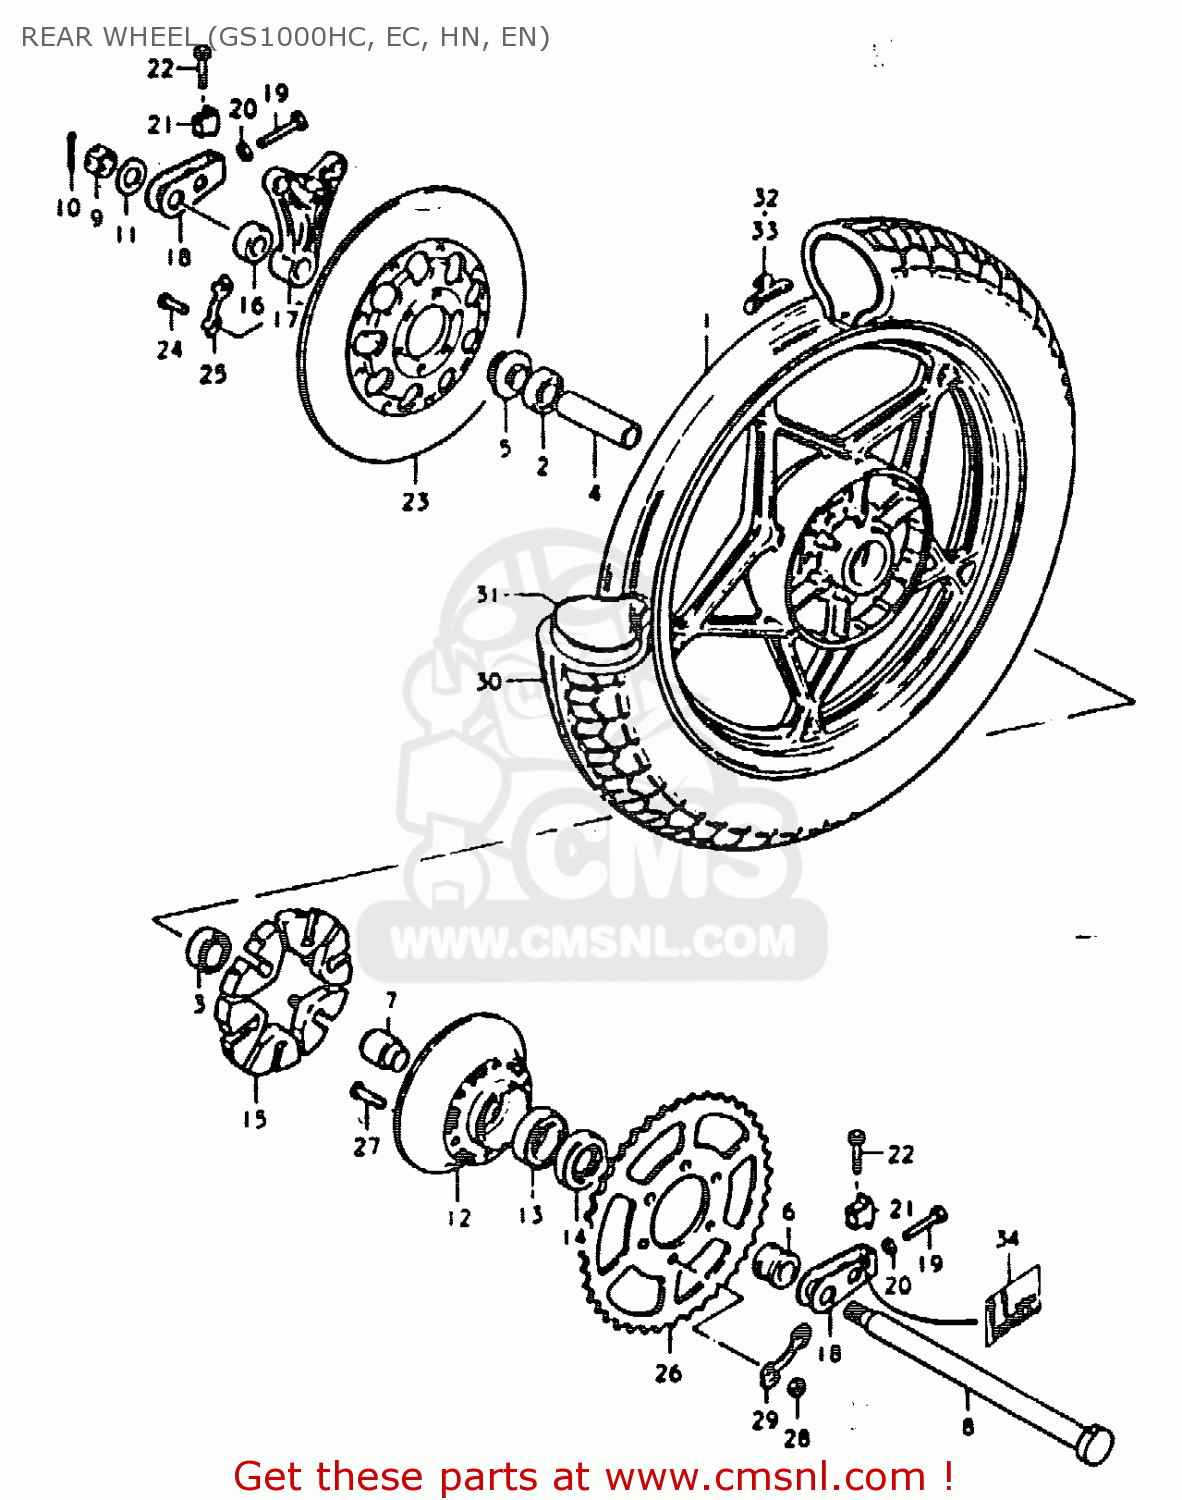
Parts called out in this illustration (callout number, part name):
1	WHEEL,REAR
2	BEARING, RH
3	BEARING, LH
4	SPACER(20.5X28X88)
5	SPACER,REAR AXLE
6	SPACER(20X33X28.3)
7	SPACER,REAR HUB BEARING
8	AXLE,REAR
9	NUT 18MM
10	PIN,COTTER
11	WASHER(19X34X4)
12	DRUM,REAR SPROCKET MOUNT
13	BEARING
14	SEAL,OIL(33X62X7)
15	ABSORBER,REAR HUB SHOCK
16	SPACER(20X38X12)
17	BRACKET,RR,CALIPER
18	ADJUSTER,CHAIN
19	BOLT
20	NUT
21	SUPPORTER,CHAIN ADJUST
22	BOLT (8X40)
23	DISC,BRAKE
24	BOLT(8X30)
25	WASHER
26	SPROCKET,REAR
28	NUT
29	WASHER
30	TIRE
31	TUBE ASSEMBLY,WHEEL,INNER
32	BALANCER,WHEEL
33	BALANCER,WHEEL
34	LABEL,CHAIN WEAR INDICATOR
